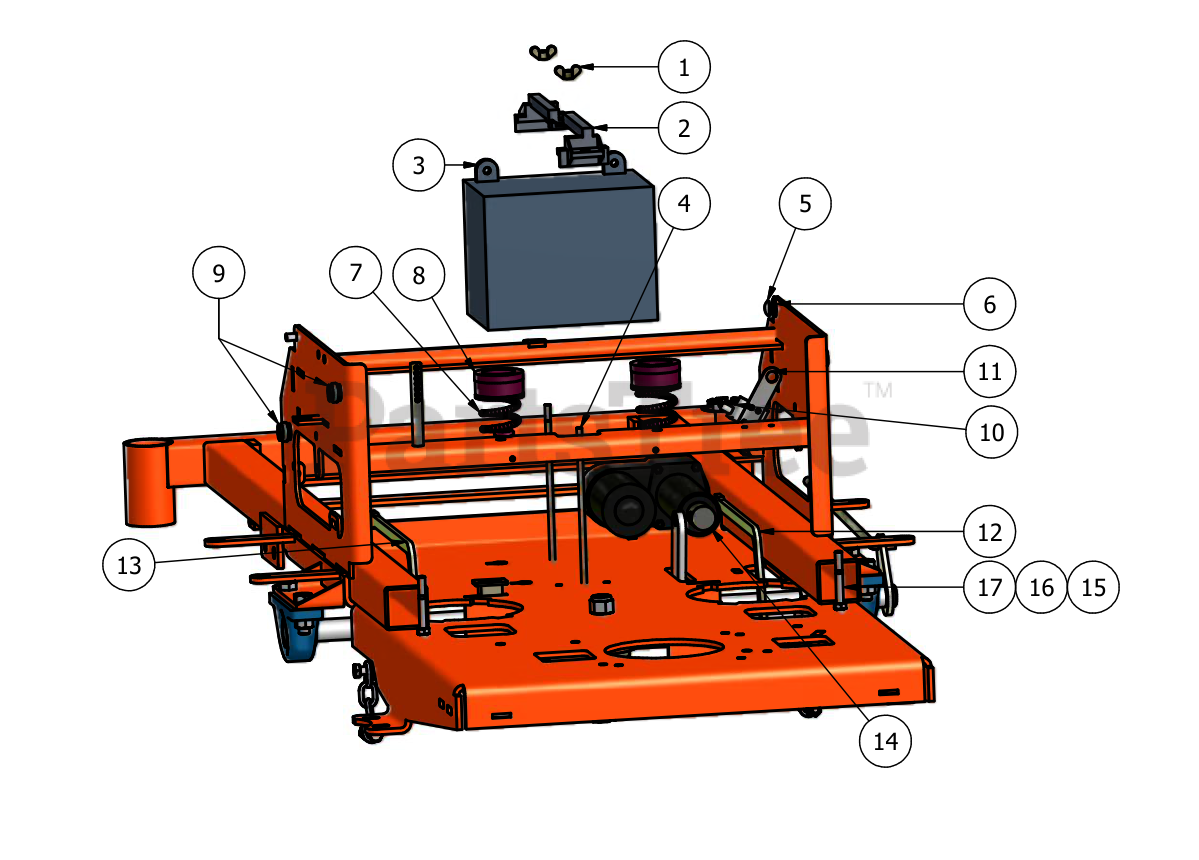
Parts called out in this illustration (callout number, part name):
1	1/4" Battery Wing Nut
2	Battery Holder
4	Stove Bolt
5	5/16" x 3/4" Carraige Bolt
6	.360" ID Nylon Washer
7	Seat Spring
8	Seat Bumper
9	1/2" Tank Spacer
11	Switch Bracket
12	Transaxle Drive Rod Right
13	Transaxle Drive Rod Left
14	Actuator For ZT
15	5/16" x 3" Hex Bolt
16	5/16" Lock Washer
